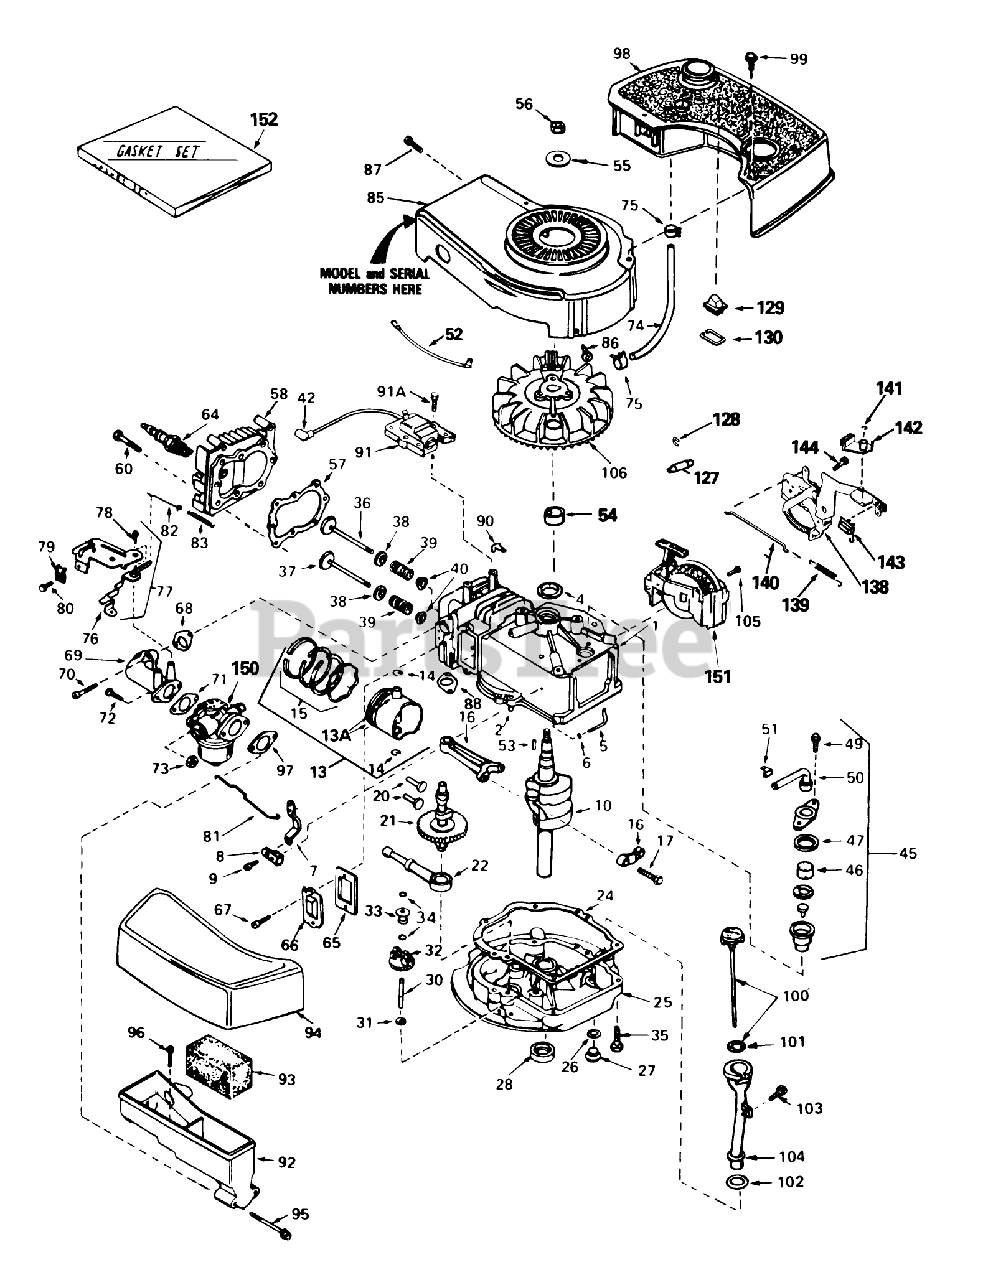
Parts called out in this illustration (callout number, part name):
1	Cylinder Assy. (Inc. #2 4)
2	Pin-Dowel
4	Seal-Oil
5	Rod, Governor (Incl. No. 36)
6	Washer-Flat
7	Governor Lever
8	Clamp-Lever, Governor
9	Screw
10	Crankshaft
13	Piston, Pin Ring Assy. (Std.) (Incl. Ref. #13A, 14 15)
13	Piston, Pin Ring Assy. (.010 oversize) (Incl. Ref. #13A, 14 15)
13	Piston, Pin Ring Assy. (.020 oversize) (Incl. Ref. #13A, 14 15)
13A	Piston Pin Assy. (Incl . Ref. . #14) (Std.)
13A	Piston Pin Assy. (Incl. Ref. #14) (.010 Oversize)
13A	Piston Pin Assy. (.020 oversize) (Incl. Ref. #14)
14	Ring-Retaining, Piston Pin
15	Ring Set (Std.)
15	Ring Set (.020" OS)
15	Ring Set (.010" OS)
16	Rod Assy., Connecting (Incl. Ref. #17)
17	Bolt-Rod, Connecting
20	Lifter-Valve
21	Camshaft(Mech.Comp. Release)
22	Oil Pump ASM
24	Gasket, Mounting
25	Flange Assy., Mounting (Incl. Ref. #26thru 30)
26	Gasket-Oil Drain
27	Plug Oil Drain
28	Seal Oil
30	Shaft-Governor
31	Washer-Flat
32	Governor Gear ASM
33	Spool-Governor
34	Ring-Retaining
35	Screw (1/4-20 x 1-1/4)
36	Valve, Intake (Std.) (Incl. Ref. #40)
36	Valve, Intake (1/32" oversize)(Incl. No. 40)
37	Valve, Exhaust (Std.)(Incl. No. 40)
37	Valve, Intake (1/32" oversize)(Incl. No. 40)
38	Cap-Upper Valve Spring
39	Spring-Valve
40	Cap-Valve, Spring
42	Cover-Spark Plug
45	Breather Assy. (Incl. Ref. #46 thru 51)
46	Element-Breather
47	Gasket-Breather
49	Screw (10-24 x 9/16)
50	Tube, Breaker
51	Clip, Breather
52	Ground Wire
53	Key-Flywheel
54	Spacer
55	Washer-Belleville
56	Nut-Flywheel
57	63573 GIL 42 SNWTHW
58	Head-Cylinder
60	Screw (5/16-18x1-1/2)
64	Plug, Spark (J17LM or equiv.)
64	Plug, Spark (Champion RCJ-8)
65	Gasket-Breather
66	Cover-Valve
67	Screw
68	Gasket-Intake
69	Pipe, Intake (Incl. No. 68)
70	Screw (1/4-20 x 1)
71	Gasket-Carburetor
73	Nut and Lock Washer (1/4-28)
74	Line-Fuel
75	Clamp-Line, Fuel
76	Lever Control
77	Control Assy., Speed (Incl. Nos, 76, 78 89)
78	Screw, Hex Washer Hd Shoulder Self-Tap
79	Conduit
80	Screw (10-32 x 3/8)
81	Link-Throttle
82	Link Governor Spring
83	Spring Governor
85	Housing-Blower
86	Screw (1/4-20x19/32)
87	Screw (10-24 x 9/16)
88	Gasket Exhaust
90	Clip-Wire
91	Solid State
91A	Screw
92	Body Air Cleaner
93	Filer, Air
94	Cove, Air Cleaner
95	Screw Fil Hd.
96	Screw, Hex Hd.
97	Gasket-Air Cleaner
98	Tank, Fuel
99	Screw (10-32 x 35/64)
100	Dipstick, Oil (Incl. Ref. #101)(Twist Lock)
101	O-Ring
102	Gasket
103	Screw (10-32 x 1/2)
104	Tube-Oil Fill
105	Screw (1/2-20x5/8)
106	Flywheel
127	Coupling, Starter Rope
128	Staple, Rope Retainer (Strip of 25 Pieces)
129	Pulley Assy., Starter
130	Retainer, Pulley
138	Bracket Assy.
139	Spring-Extension
140	Link-Control
141	Ring-Retaining
142	Lever-Brake
143	Terminal
144	Screw-Hex. Hd.
150	Carburetor (Incl. Ref. #71)
151	Starter, Sidemount rewind
152	Gasket Set
